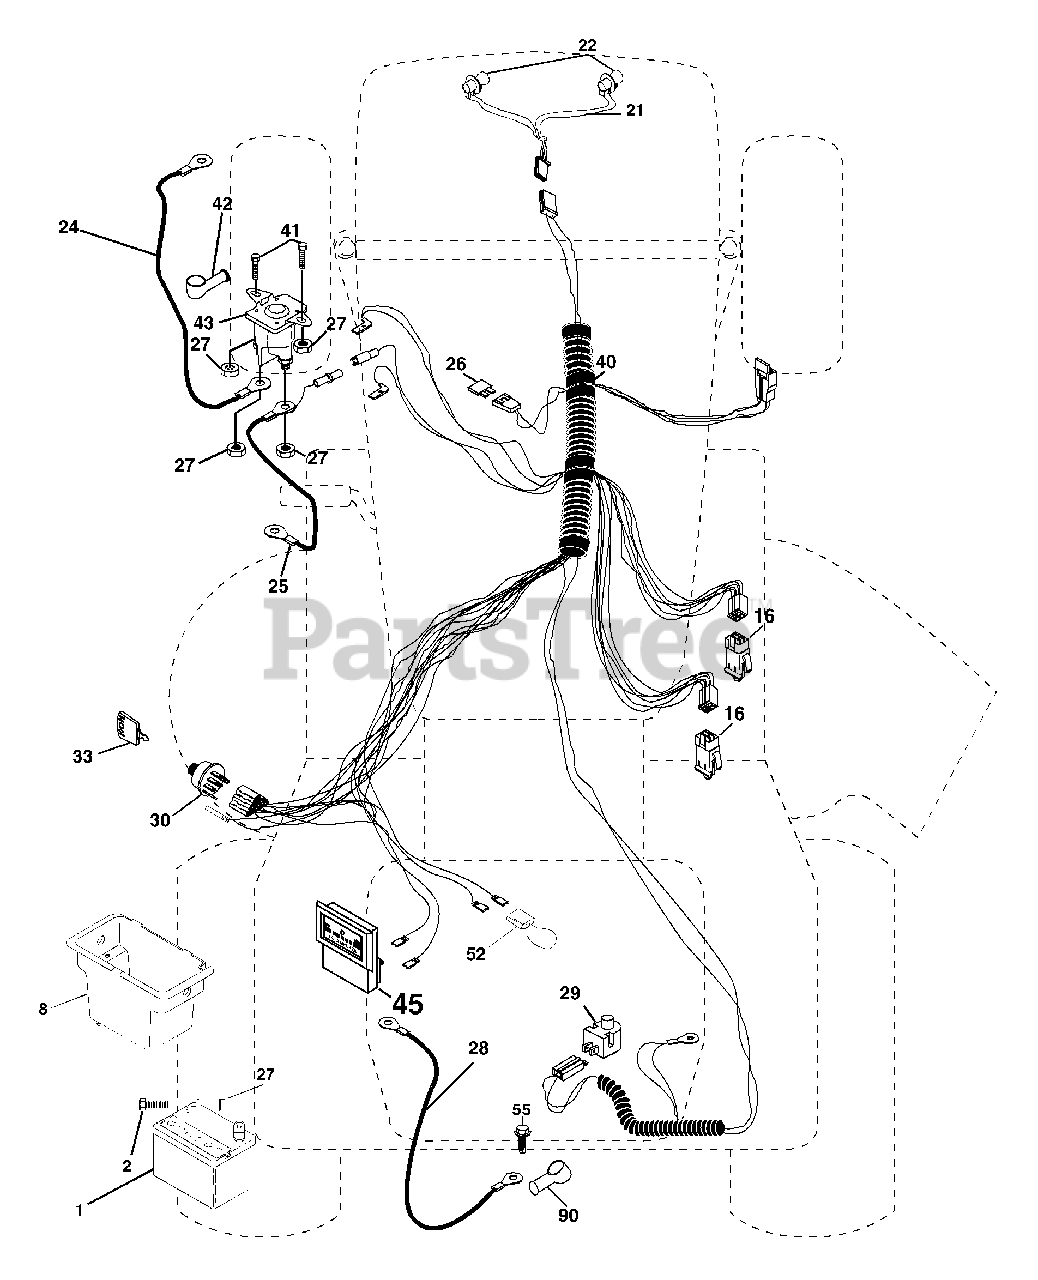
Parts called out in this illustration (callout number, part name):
1	Battery
2	Bolt Hex Hd 1/4-20 Unc x 3/4
8	Battery Box
16	Switch Interlock Push-In
21	Harness Socket Light
22	Bulb, Light # 1156
24	Cable Battery
25	Cable Battery 6 Ga Red w/16 wire
26	Fuse
27	Nut Keps Hex 1/4-20 Unc
28	Cable Ground 6ga 12 black
29	Switch Plunger Nc Gray
30	Switch Ign
33	Key Ign Molded Generic
40	Harness Ign
41	Bolt Fin Hex 1/4-20 Unc x 1/2
42	Cover Terminal Red
43	Solenoid
45	Ammeter Rectangular
52	Protection Loop
90	Cover Terminal
